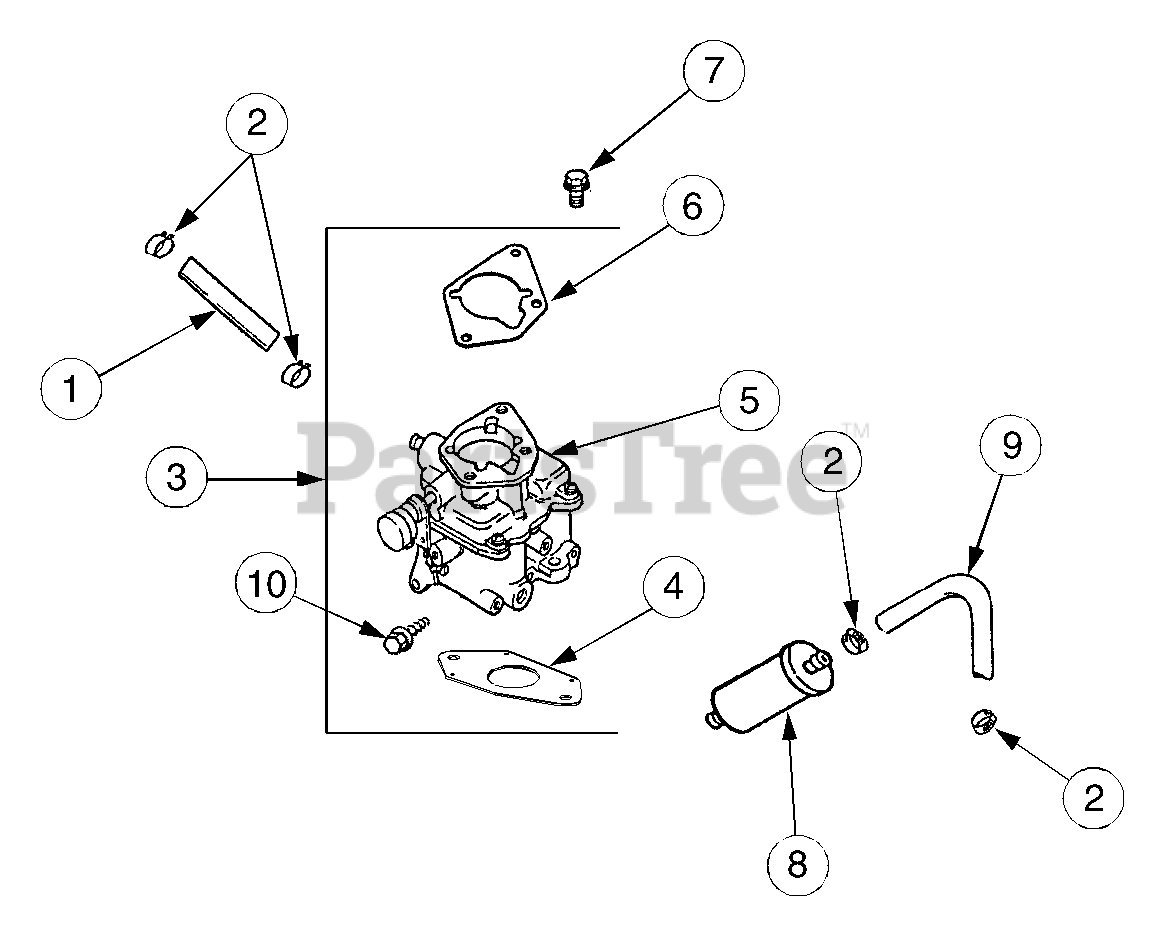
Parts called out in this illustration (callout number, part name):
1	Line, Fuel 10"
2	Clamp, Hose
3	Kit, Carburetor w/Gasket
4	Gasket, Carburetor
5	Carburetor Assembly
6	Gasket, Air Cleaner Base
7	Screw, Hex Flange, M6 x 1.0 x 25
8	Filter, Fuel
9	Line, Fuel 11"
10	Screw, Throttle Stop
